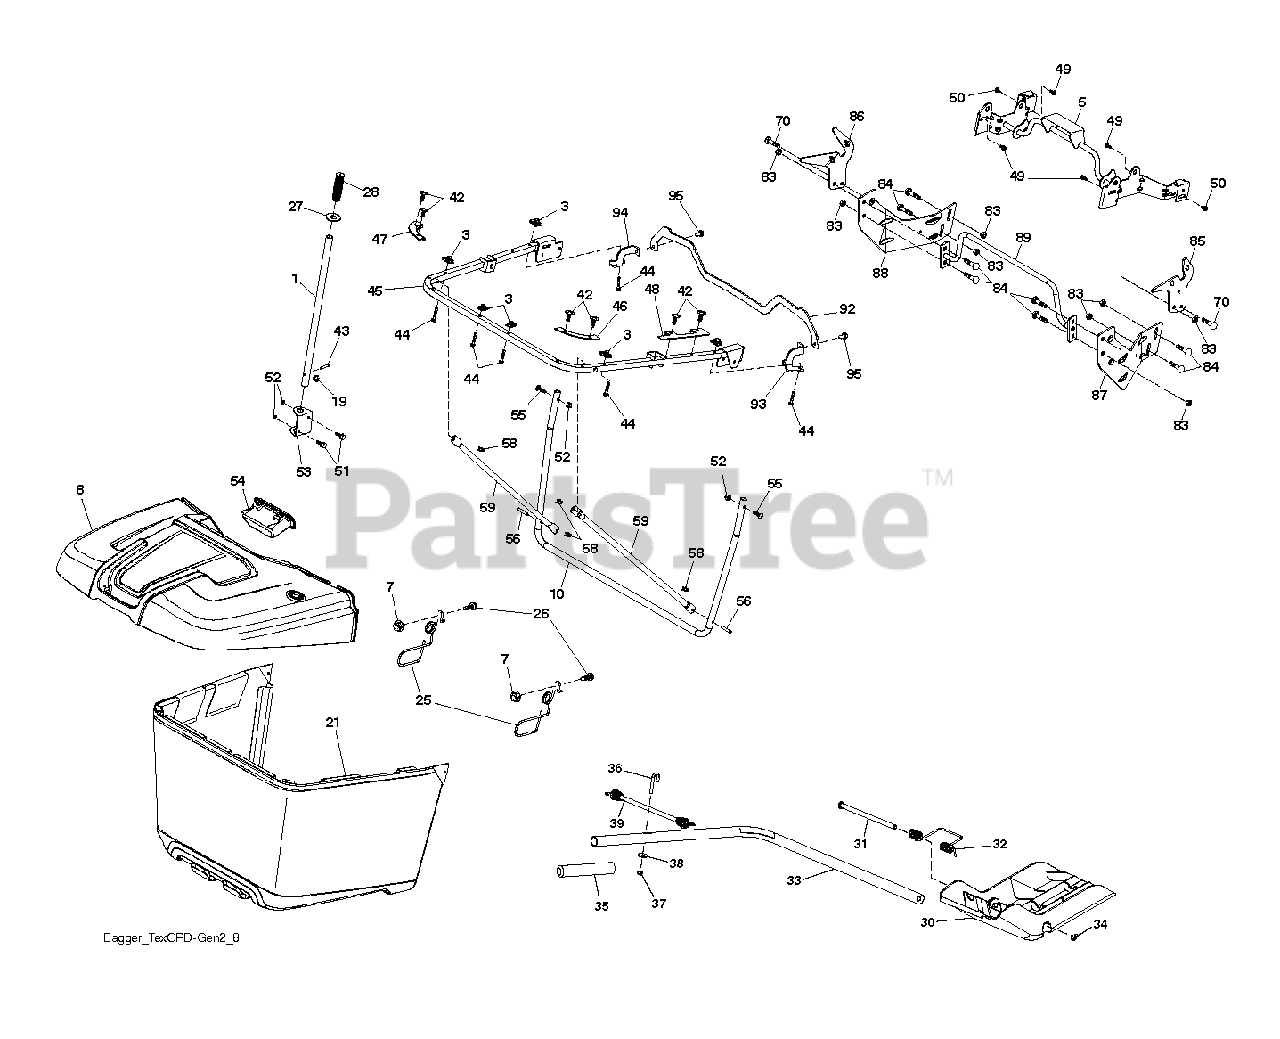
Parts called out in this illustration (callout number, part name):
1	TUBE.PNT.HDL.BAGGER.
3	1/4-20 U NUT
7	NUT T
19	PIN.COTTER.5/16.BOW TI
26	SCREW HEX CRT
28	GRIP.HANDLE.BLACK
34	E-RING.5/16"
38	WASHER
43	RIVET,DRILLED
49	BOLT, SHOULDER 5/16-18
50	BOLT, 5/16-18 X 1 3/4
52	NUT.71038.31-18.HEX.NYLOCK
56	PIN.CLEVIS.183
58	RETAINER CLIP PM
70	SCREW, 3/8-16X3/4
83	NUT
92	BRACKET.PNT.BAGGER.TOP.SUPPORT
93	BRACKET.PNT.RH.SUPPORT.ATTACH
94	BRACKET.PNT.LH.SUPPORT.ATTACH
95	SCREW
